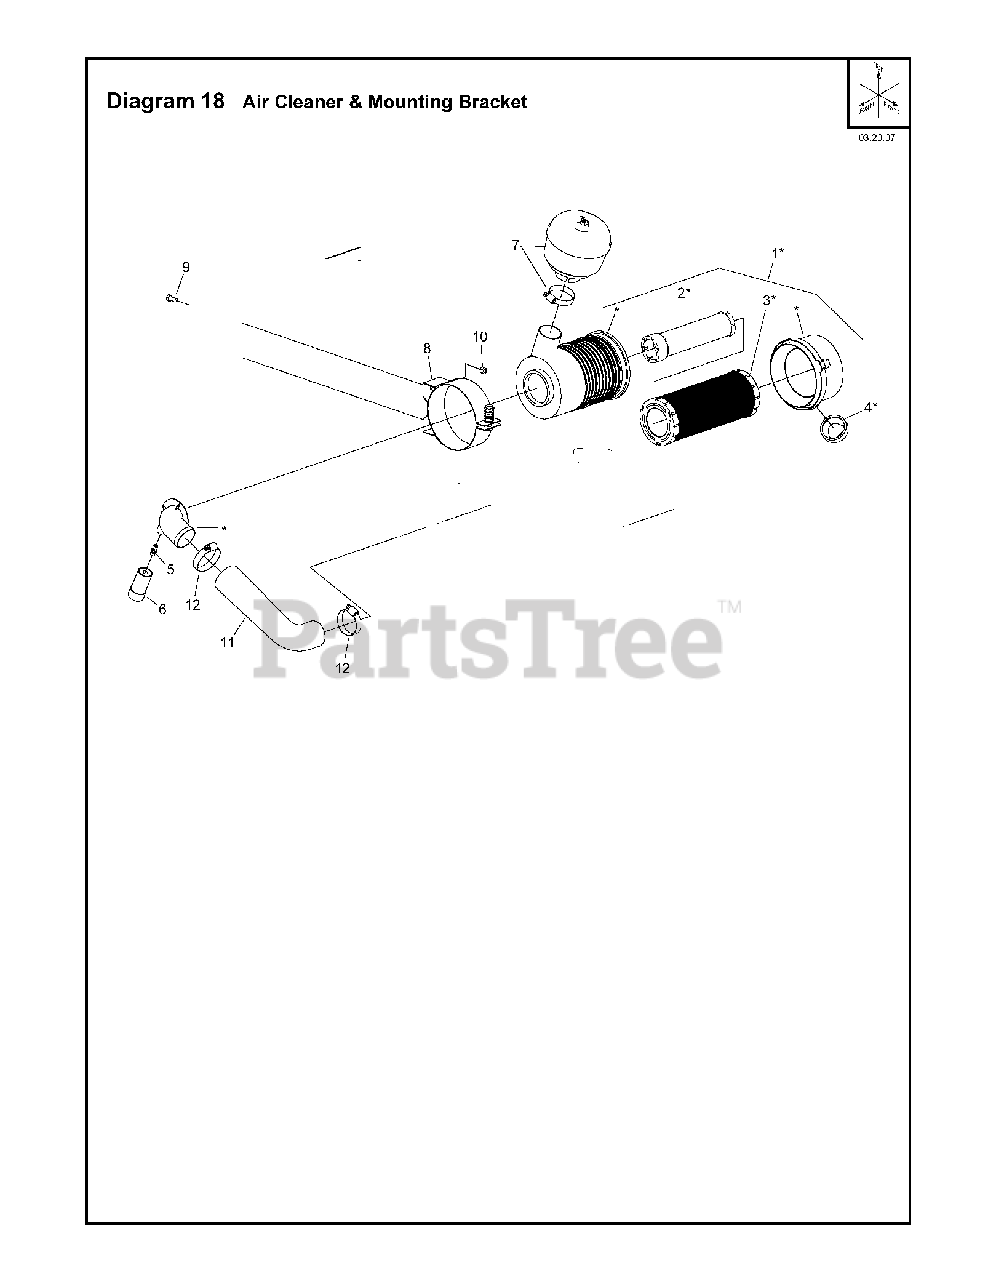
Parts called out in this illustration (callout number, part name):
1	AIR CLEANER
3	GEARCASE.ASM.LH.W/BEARING
4	ETL RALLY REQ1136A
5	SCREW
6	DECAL
7	PRE-FILTER ASSEMBLY
8	BAND. MTG. AIR CLEANER
9	HHCS. M8 x 1.25 x 20 DIN933 ZP
10	LOCKNUT. FIBER M8 DIN 985 Z/P
11	GBAG.250C2.BLK.PP/STRP
12	HOSE CLAMP. WORM DRIVE SAE32
